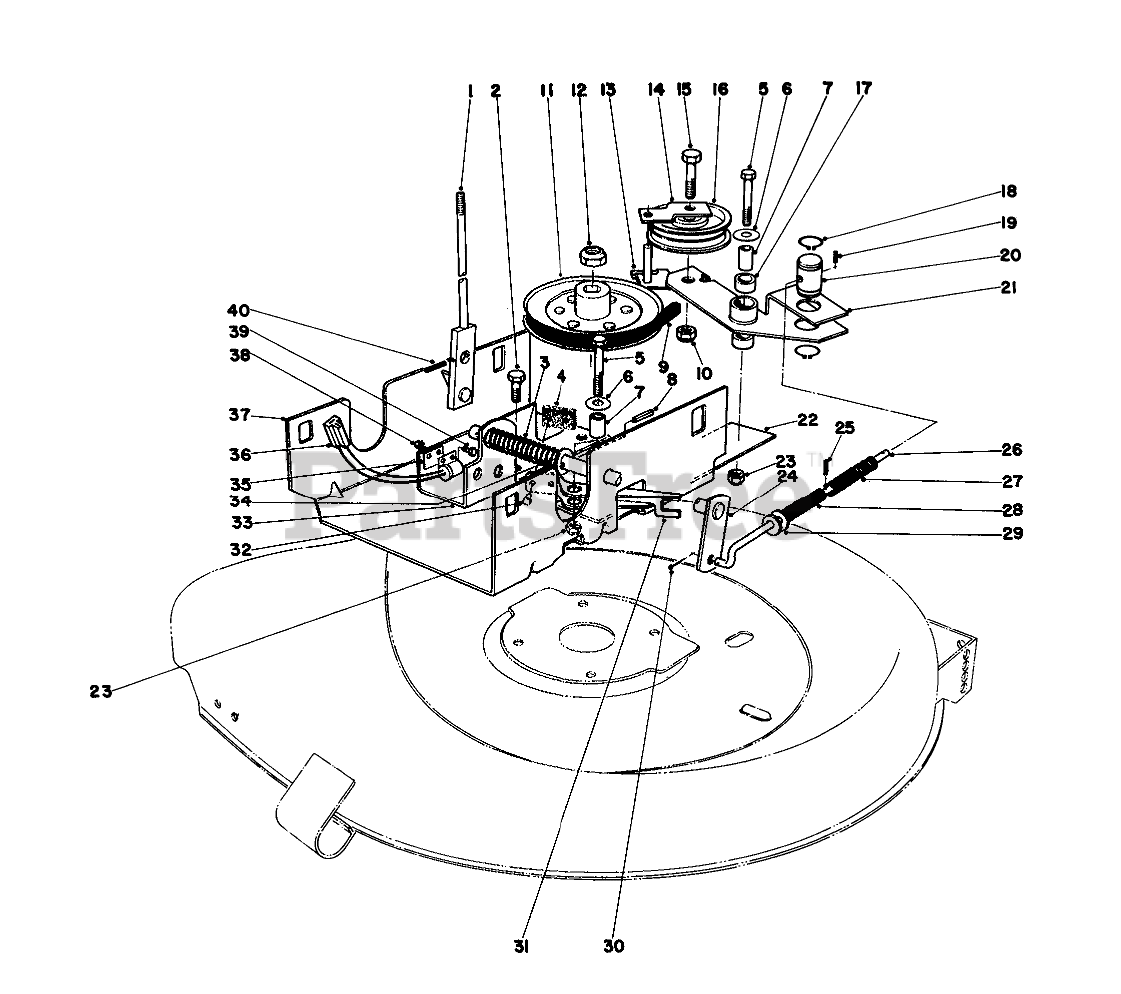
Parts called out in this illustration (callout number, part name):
1	Lever Deck Engagement
2	SCREW-HH
3	COMP SPRING O
4	BLADE BRAKE LINING
5	SCREW-HH
6	WASHER-PLAIN
7	PIVOT SPACER
8	PIN-SPRING
9	V-BELT
10	NUT-LOCK, SIDE
11	DECK PULLEY R
13	Belt Retainer
14	BELT RETAINER UPPER
15	SCREW-HH
16	Flat Idler
17	Bushing
18	RING-RETAINING
19	PIN-ROLL
20	Pin-Pivot
21	Idler Arm (Incl. Ref. #17)
22	Bracket Idler Mounting
23	NUT-LOCK, CONE
24	Linkage
25	PIN-SPRING
26	BLADE ENGAGE ROD
27	Spring Deck Idler
28	Spring Deck Brake
29	WASHER
30	PIN-COTTER
31	Blade Brake (Incl. Ref. #4 & 32)
32	Rivet
33	Mounting Bracket Blade
34	WASHER-FLAT
35	Spacer Switch
36	DECK INTERLOCK SWITCH
37	CHANNEL HT ADJ R
38	NUT-KEPS
40	PIN-SPIRAL
